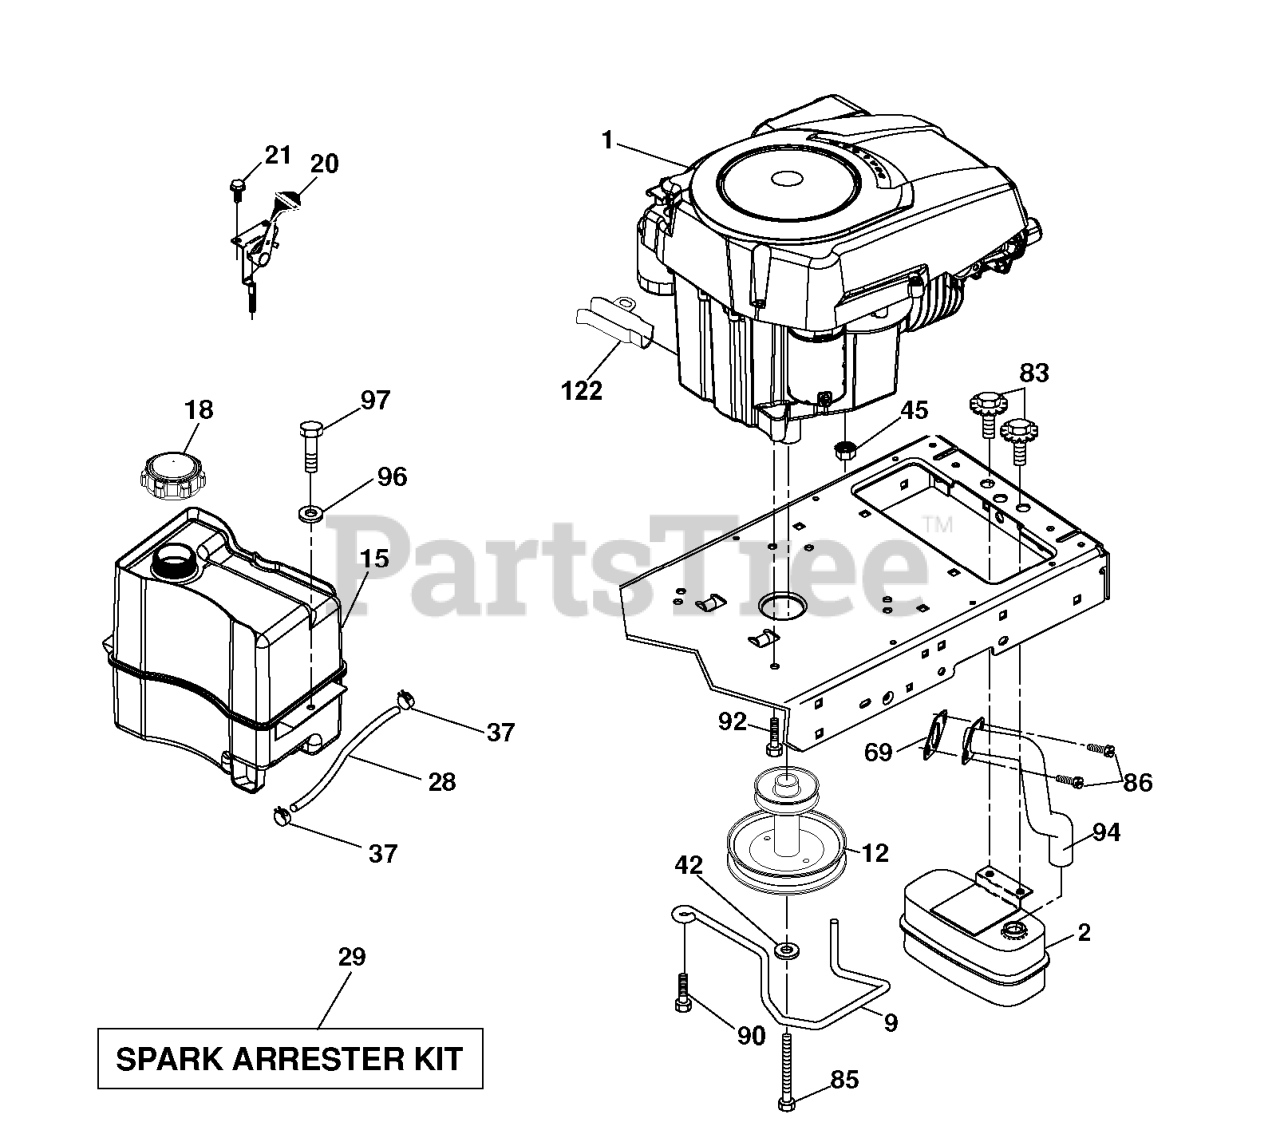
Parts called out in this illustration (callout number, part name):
2	MUFFLER.SINGLE.CYL.KOHL/B&S
9	KEEPER.BELT.ENGINE.4.2
12	PULLY ENGINE
15	RP TANK FUEL FRT 1.5 GAL
18	CAP ASM.FUEL.2.25"FR.
20	CONTROL.TH/CK.C.
21	SCREW.#10 X 0.750.BOS
28	LINE.FUEL.20
29	KIT.SPARK ARRESTOR 794945 B&S
37	HOSE CLAMP
42	LOCKWASHER
45	NUT
69	GASKET.EXHAUST.KOHLER
83	BOLT.5/16-18UNCX3/4 W/SEMS.BLK
85	BOLT HEX 7/16-20X4-1/4"
86	SCREW.SOCKET HD.5/16-1
90	SCREW 3/8-16X1
92	SCREW 3/8-16X1
94	RP.TUBE.EXHAUST.KOHL.COURAGE
97	SCREW HEXWSHR 1/4-20X3/4
122	EXTENSION DRAIN OIL
